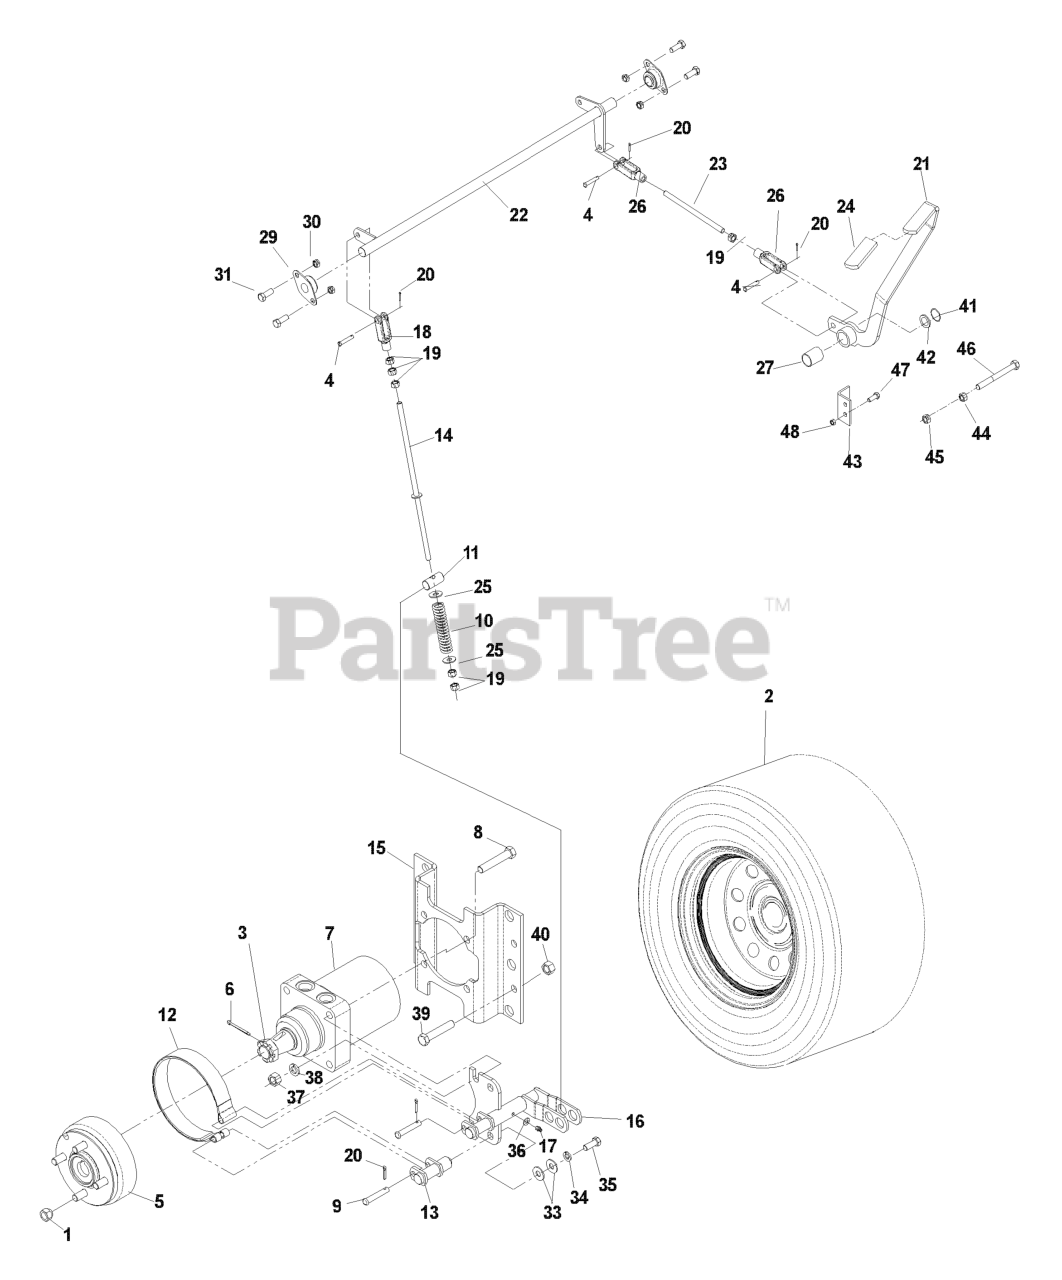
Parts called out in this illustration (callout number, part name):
1	LUG NUT 1/2F
2	WHEEL/TIRE.ASM.23X10.5-12.GREY
2	TIRE.TURF.MASTER.23X10.5-12
2	RIM 0 OFFSET 8.5" WIDE
2	VALVE STEM TR-412
2	RP WHEEL.ASM.23X10.5-12.TURFMA
2	WHEEL/TIRE.ASM.24X12-12.SILVER
3	NUT 3/4-16 HEX SLTD GR5 ZD
4	CLEVIS PIN 3/8 X 1 1/8
5	HUB W/BRAKE DRUM
6	PIN COTTER 4MM X 45MM
7	MB WHEEL MOTOR
8	HCS 1/2C X 2 3/4
9	CLEVIS PIN
10	COMPRESSION SPRING
11	TRUNION PIN
12	BRAKE BAND
13	BRAKE BAND SUPPORT
15	MOTOR STANDOFF
16	BRAKE WLDMNT
17	ZERK
18	YOKE-3/8-24 PLTD
20	RP_COTTER PIN 1/8 X 3/4
21	BRAKE LEVER WLDMT
22	BRAKE CROSS SHAFT
23	LINKAGE - SHORT
24	GRIP, PARK BRAKE
25	WASHER, 7/16 DISC SPRING
26	YOKE-3/8-24 PLTD
29	FLANGE BEARING
30	NUT 3/8-16 NYLOC
31	HCS 3/8-16X1.GRD.5.ZD
32	RP_COTTER PIN 1/8 X 3/4
33	WASHER 3/8 FLAT
34	SLW 3/8 STD
35	HEX BOLT 3/8 X 1"
37	NUT HEX 1/2
38	WASHER 1/2" SPLIT LOCK
39	HCS 1/2C X 1 1/4 SERRATED HEAD
40	NUT 1/2-13 HEX NYLOC ZD
41	RETAINING RING, 7/8"
42	BSHG .875 X 1.375 X .074 ZD
44	NUT 3/8C WHIZ
45	NUT 3/8-16 NYLOC
46	HCS 3/8C X 2 1/2
47	HCS 1/4C X 3/4 HCS
48	NUT.1/4-20.HEX.NYLOC.ZD
